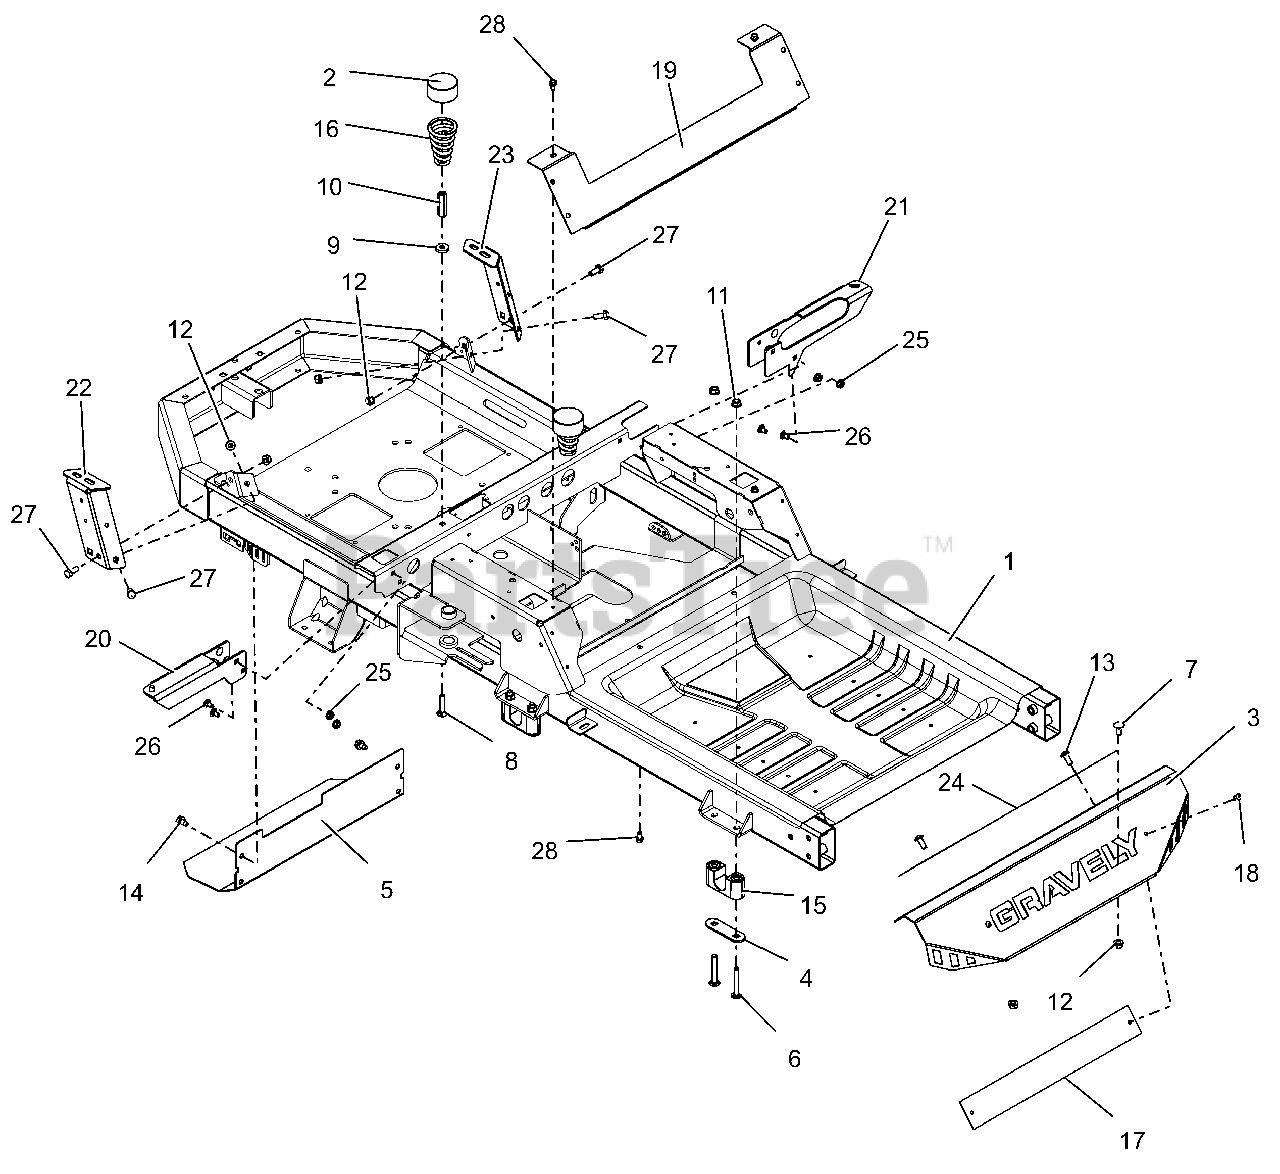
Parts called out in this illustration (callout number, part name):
1	KIT, ZT-X/XL FRAME SERVICE
3	KIT, FOOTPLATE W/DECAL-ZTX
4	PLATE, BEARING SUPPORT
5	HEAT, SHIELD
6	BLT, RHSSN.31-18X2.25 G5 ZCC
7	BLT,RHSN .31-18X.75 G5 ZCC
8	BLT,RHSN .31-18X1.50 G5 ZCC
9	WSHR, FLT .328X.870X.179 ZCC
10	NUT, COUPLING .31-18X1.75 ZCC
11	NUT,LK-CTR-FLG .31-18 GF ZCC
12	NUT-LK-TOP-FLG .312-18 GF ZCC
13	SCR-RDHDSKTAP .31-18X.75
14	SCR,TAP .312-18X.50 HWH TR ZCC
15	BSHG, DECK LIFT PIVOT
16	SPRING, SEAT
17	PLATE, BACK FOOT-REST XL
18	RIVET, #66 STEEL POP PD BLACK
19	PLATE, SEAT KICK
20	BRKT,CROSS EXTENSION - LH
21	BRKT,CROSS EXTENSTION - RH
22	MOUNT,FENDER-RH EXTENSION
23	MOUNT,FENDER-LH EXTENSION
24	GRIP, FOOT PLATE
25	NUT-LK-CTR-FLG .25-20 ZC120
26	BLT, RHSSN.25-20X.500 G5 ZCC
27	BLT,HEX .31-18X.75 G5 ZCC
28	SCR-TAP .25-20X.50 HWH ZCC
